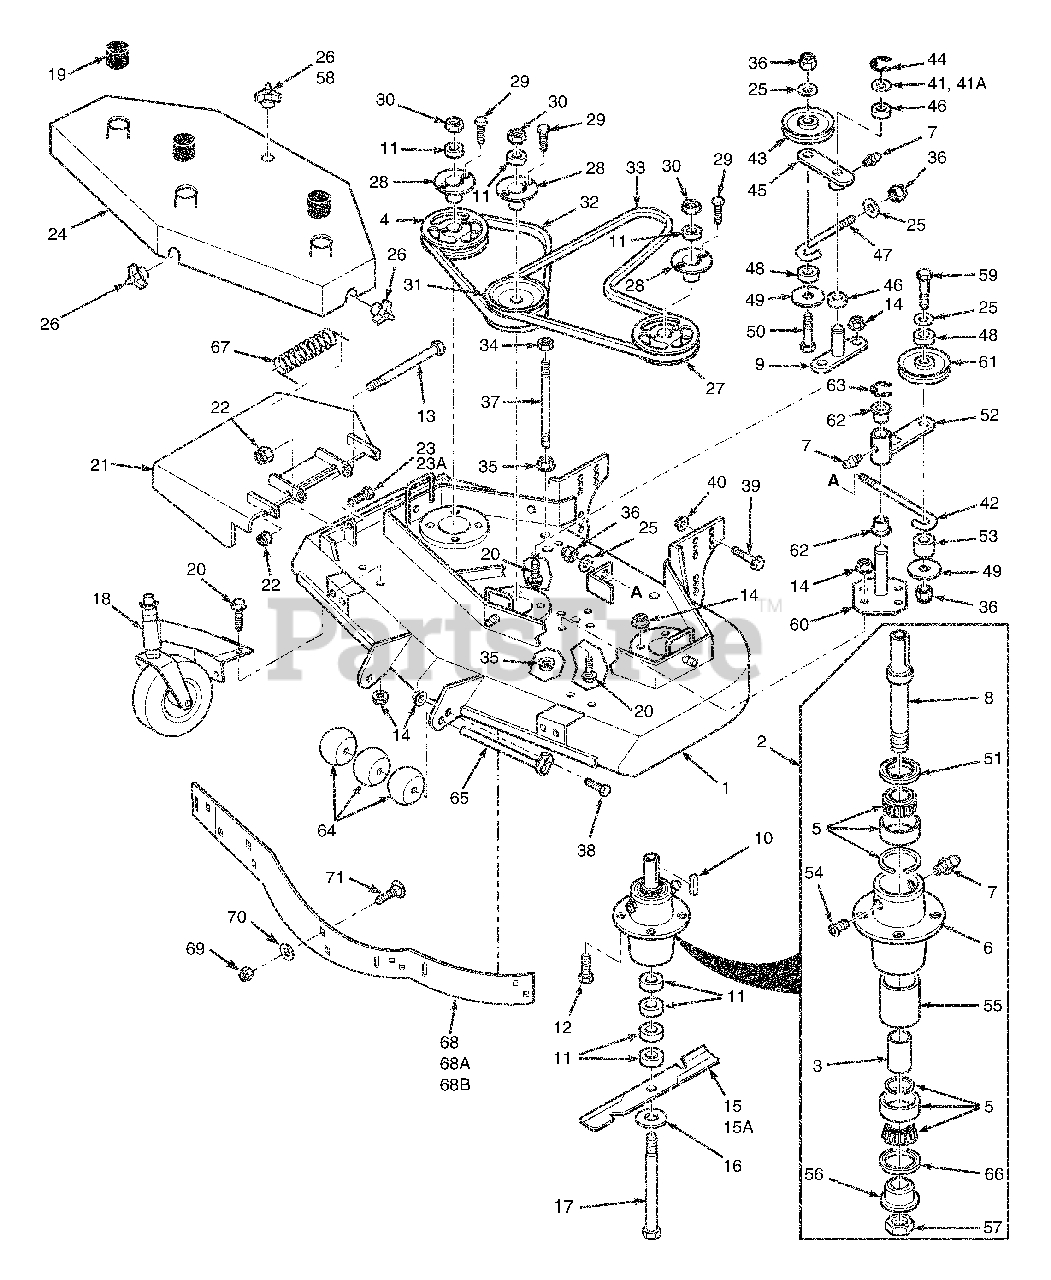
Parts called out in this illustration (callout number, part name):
1	Cutter Deck
2	Spindle Assembly
3	Spacer, Inside
4	Pulley
5	Tapered Bearing (Two)
6	Spindle Housing
7	Grease Fitting Str. 5/16
8	Spindle Shaft, Tapered Brng
9	Idler Pivot
10	Key, 1/4 x 1/4 x 2"
11	Spacer, Cutter Blade - Small
12	Bolt, 5/16-18 x 1-1/4" Hex Head
13	Bolt, 5/16-18 x 4-3/4" Hex Head
14	Serrated Flange Nut, 5/16-18
15	Cutter Blade 18"
15A	Cutter Blade 18" Hi Lift
16	Flatwasher,5/8" (.688 x 1.75 x .134)
17	Hex Head Bolt, 5/8-11 x 9-1/2"
18	Caster Assembly
19	Spindle Shield
20	Capscrew, 5/16-18 x 3/4"
21	Discharge Chute
22	Nut, 5/16-18 Elastic Elastic Stop
23	Bolt, 5/16-18 x 1-1/2" Hex
23A	Bolt, 5/16-18 x 1-3/4" Hex
24	Belt Cover
25	Flat Washer, 3/8" Special
26	Wing Nut, 3/8-16 (Large)
27	Pulley
28	Tapered Hub
29	Bolt, 1/4-20 x 3/4" Hex Head
30	Nut, 5/8-11 Hex
31	Pulley, Double
32	Belt, RH Blade Drive
33	Belt, Blade Drive
34	Nut, 3/8-16, Nut Centerlock
35	Nut, 3/8-16, Serrated Flange
36	Nut, 3/8-16 Elastic Stop
37	Support, Belt Cover
38	Bolt, 5/16-18 x 1" Hex Head
39	Cpscrw,1/2-13 x 1" Ser Flng Hex Hd
40	Nut, 1/2-13 Spiralock
41	Flat Washer 3/4" Special
41A	Flat Washer 3/4" Special
42	J-Hook
43	Idler Pulley, "V" Groove
44	Retaining Ring, 3/4" Ext."E"
45	Idler Arm Assy.
46	Bronze Bearing
47	J-Rod, Idler Pulley
48	Spacer, J-Rod
49	Washer, 3/8 x 1-1/2 x 16 ga.
50	Bolt, 3/8-16 x 2-1/4" Hex Head
51	Seal, Cutter Spindle
52	Idler Arm Assy
53	Spacer, J-Rod
54	Relief Fitting, Cutter Spindle
55	Spacer, Outside, Cutter Spindle
56	Spindle Bushing
57	Nut, Cutter Spindle
58	Wing Nut, 3/8-16 (Small) Top Side
59	Bolt, 3/8-16 x 3-1/2" Hex Head
60	Idler Pivot
61	Idler Pulley, Belt Clutch
62	Bronze Bearing
63	Retaining Ring
64	Guide Roller
65	Roller Shaft
66	Seal, Cutter Spindle
67	Spring, Chute Return
68B	Baffle Weldment 61A
69	Nut, Hex Elastic Stop 3/8-16
70	Flatwasher, 3/8" (.391 x .938 x .105)
71	Bolt, Carriage 3/8-16 x 1"
